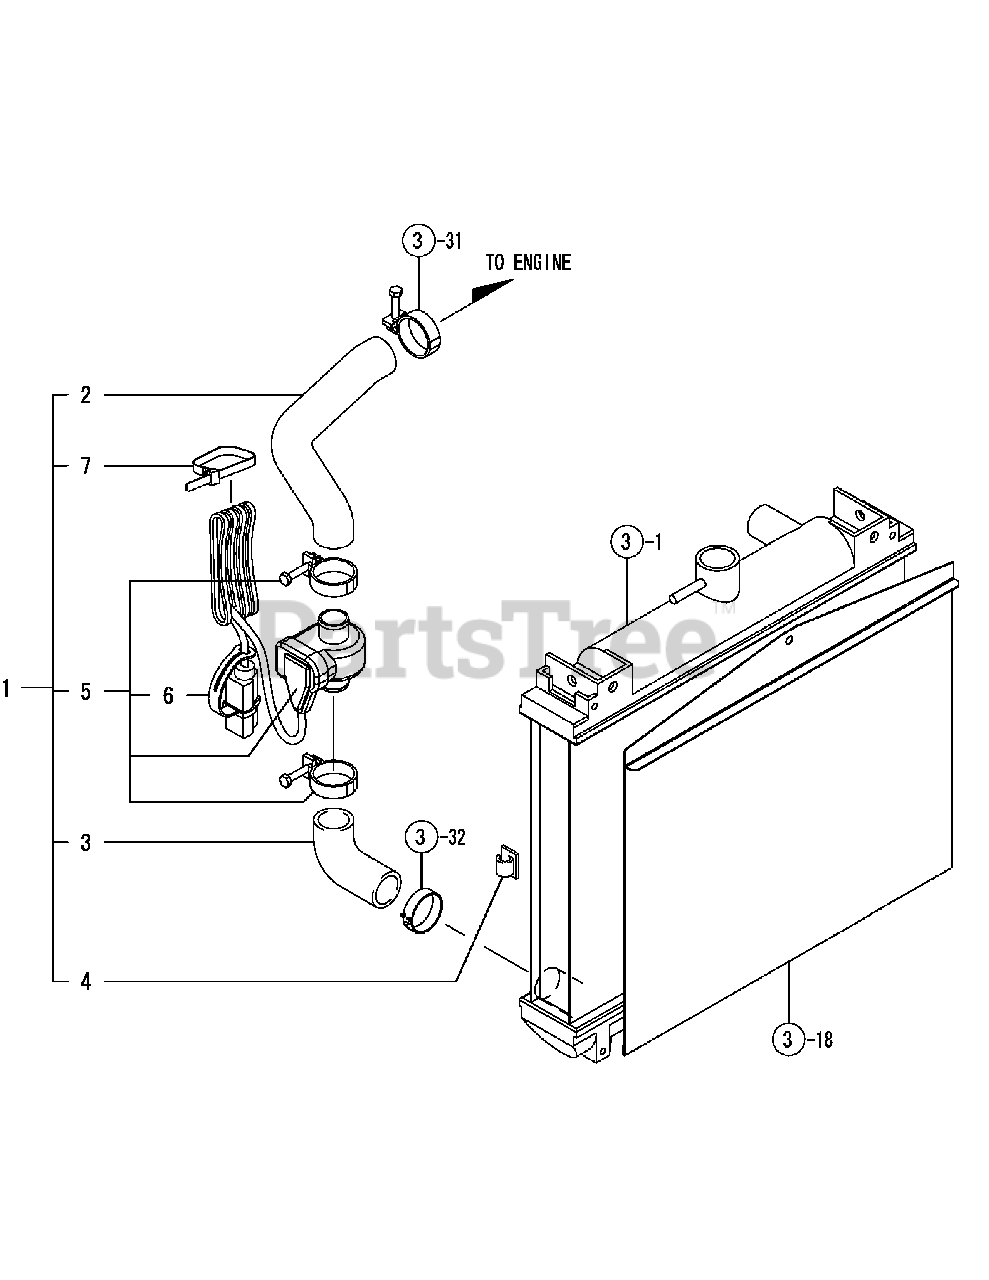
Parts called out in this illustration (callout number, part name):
1	HEATER KIT, RADIATOR
2	HOSE U, COOLING WATER
3	HOSE L, COOLING WATER
5	HEATER, RADIATOR HOSE
6	PLUG PROTECTOR
